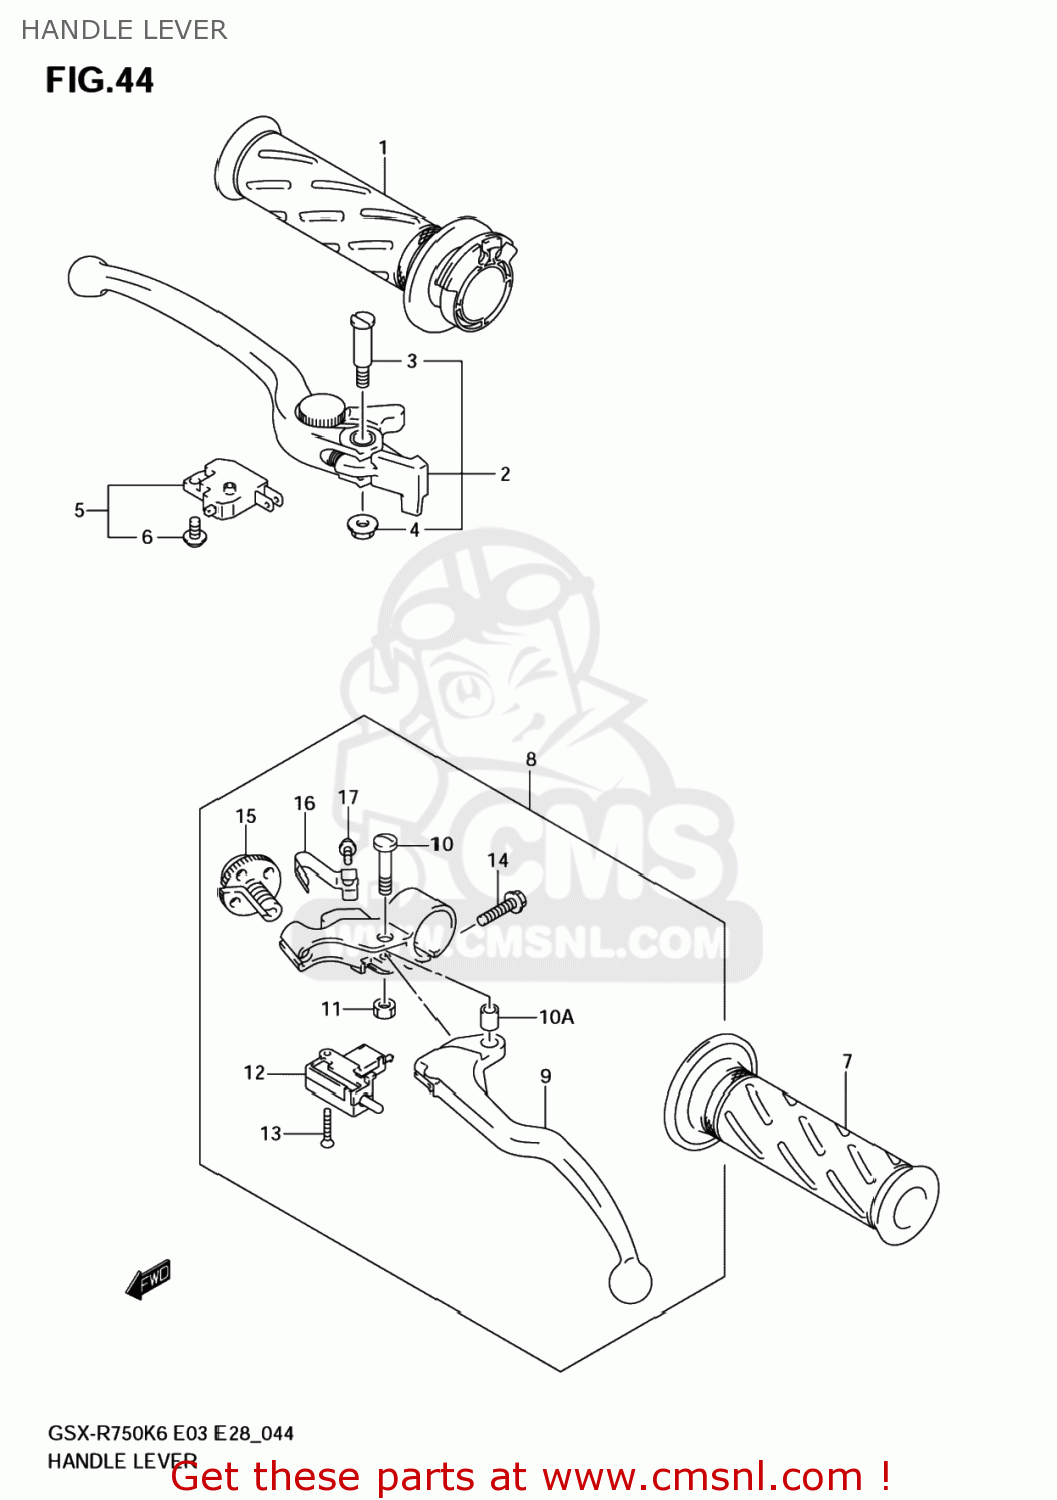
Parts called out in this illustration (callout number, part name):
1	GRIP COMP,THRO
2	LEVER ASSY,BRA
3	BOLT,LEVER PIVOT
4	NUT,LEVER PIVOT
5	SWITCH ASSY,ST
6	SCREW
7	GRIP,LEFT
8	LEVER ASSY,CLUTCH
9	LEVER,CLUTCH
10	BOLT,CLUTCH LEVER PIVOT
10A	COLLAR
11	NUT
12	SWITCH,CLUTCH
13	SCREW
14	SCREW
15	NUT,ADJUSTER
16	SPRING,ADJUST
17	SCREW,SPRING
